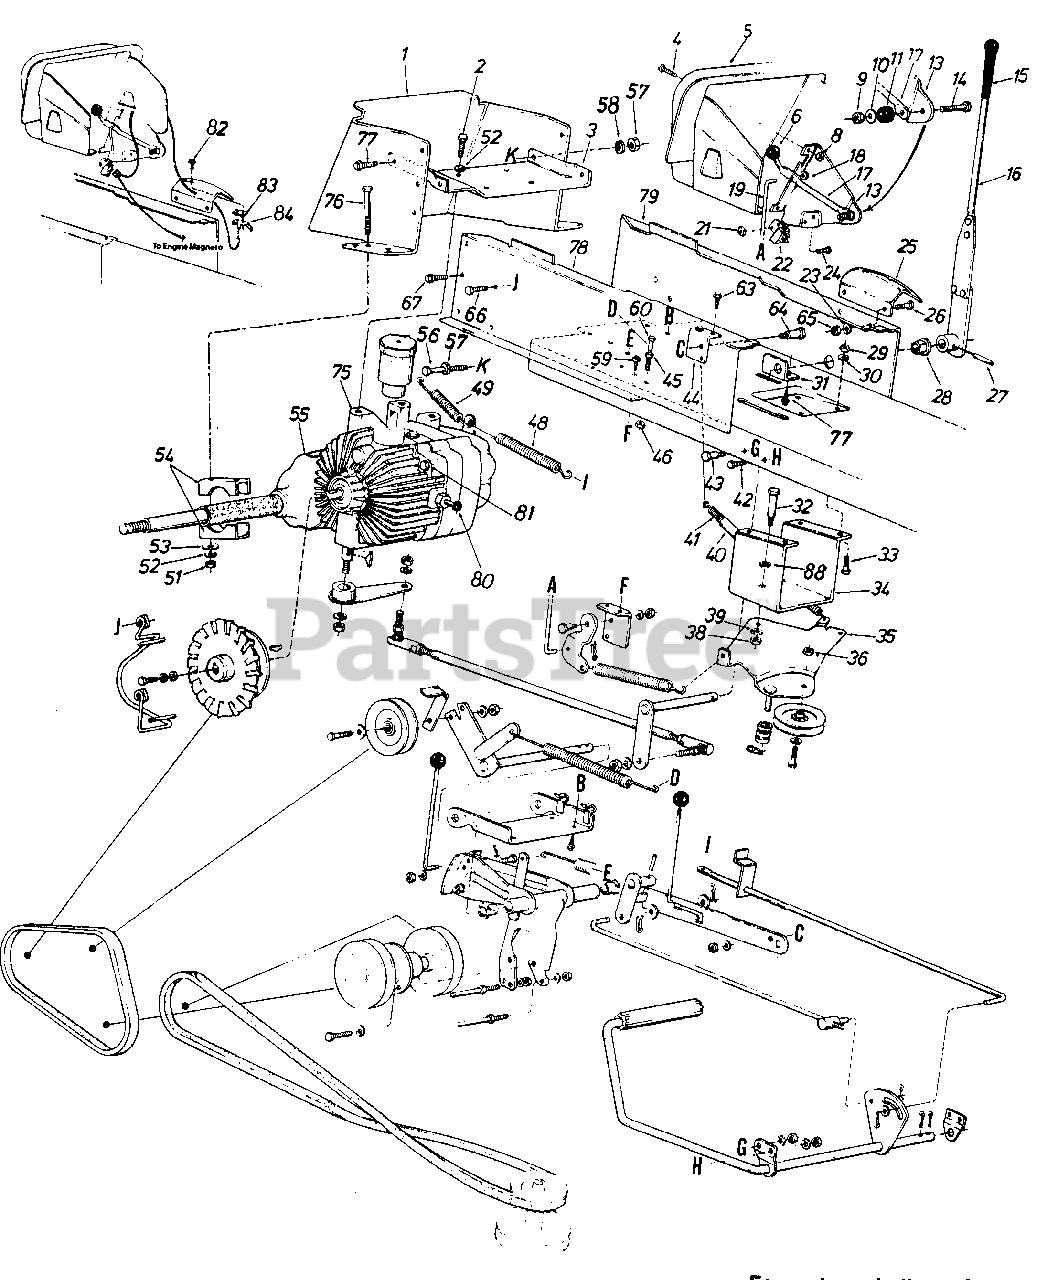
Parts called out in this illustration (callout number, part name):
1	Hitch Plate
2	Hex Bolt 3/8-16 x .75" Lg.*
3	Rear Axle Support Brkt.
4	Truss Mach. Scr. 1/4-20 x .50" Lg.*
5	Dash Panel Ass'y.
6	Knob-Blade Clutch
8	Hex Sems Nut 1/4-20 Thd.
9	Hex Cent. L-Nut 1/4-20 Thd.
10	Fl-Wash. .28" I.D. x .74" O.D. x .063
11	Rubber Wash. .33" I.D. x .87" O.D. x .30
13	Deck Clutch Cont. Brkt.
14	Hex Bolt 1/4-20 x 1.25" Lg.*
16	Control Arm Ass'y.
17	Blade Clutch Lever
18	Push Nut 1/4" O.D. Rod
19	Deck Control Rod
21	Hex Nut #10-24 Thd.
22	Safety Switch
23	L-Wash. 5/16" I.D.*
24	Truss Mach. Scr. #10-24 x .50" Lg.*
25	Speed Control Bracket
26	Hex Bolt 5/16-18 x .62" Lg.
27	Spring Pin Spiral 1/4" Dia. x 1.5" Lg.
28	Hex Flange Brg.
29	He) t Nut 5/16-18 Thd.
30	L-Wash. 5/16" I.D.*
31	Speed Control Shaft Brkt.
32	Shld. Scr. .437" Dia. x .162" Lg.
33	Hex Bolt 5/16-18 x 1.00" Lg.
34	Idler Support Brkt.
35	Idler Brkt. Ass'y.
36	Hex L-Nut 3/8-16 Thd.
38	Hex Nut 5/16-18 Thd.
39	L-Wash. 5/16" I.D.*
40	Convoluted Conduit .50" I.D.
41	Ext. Spring .50" O.D. x 6.37" Lg.
42	Hex Bolt 3/8-16 x .62" Lg.*
43	Shld. Scr. .50" Dia. x .395" Lg. (3/8-16)
44	Parking Brake Cam Mtg. Brkt.
45	Hex Nut 5/16-28 Thd.*
46	Hex L-Nut 5/16-18 Thd.
48	Brake Tension Spring
49	Ext. Spring-Brake Return
51	Hex Nut 3/8-16 Thd.
52	L-Wash. 3/8" I.D.*
53	Fl-Wash. .390" I.D. x 1.00" O.D. x .125" Thk.
54	Rear Axle Bracket
55	Transaxle
56	Hex Bolt 1/4-20 x 2" Lg.
57	Hex Nut 1/4-20 Thd.
58	L-Wash. 1/4" I.D.*
59	Hex Wash. Hd. Self-Tap Scr. 1/4-20 x .50" Lg
60	Hex Bolt 5/16-18 x 1.50" Lg.
63	Hex Wash. Hd. Self-Tap Scr. 1/4-20 x .50' Lg.
64	Shld. Scr. .437" Dia. x .162"
65	Hex Nut 5/16-18 Thd.*
66	Hex Wash. Hd. Scr. 3/8-16 x .50" Lg.*
67	Hex Wash. Hd. Self-Tap Scr. 5/16-18 x .75" Lg.
75	Hydrostatic Pump Comp.
76	Hex Bolt 3/8-16 x 3.5" Lg.
77	Hex AB-Tap Scr. 5/16 x .75" Lg.
78	Side Panel Upper Frame R.H.
79	Side Panel Upper Frame L.H.
81	Socket Hd. Bolt 3/8-16 x 2.75" Lg.
82	Hex Wash. Hd. Scr. #8 x .50" Lg.
83	Insulator Nut Plate
84	Spring Switch
88	Wave Washer
